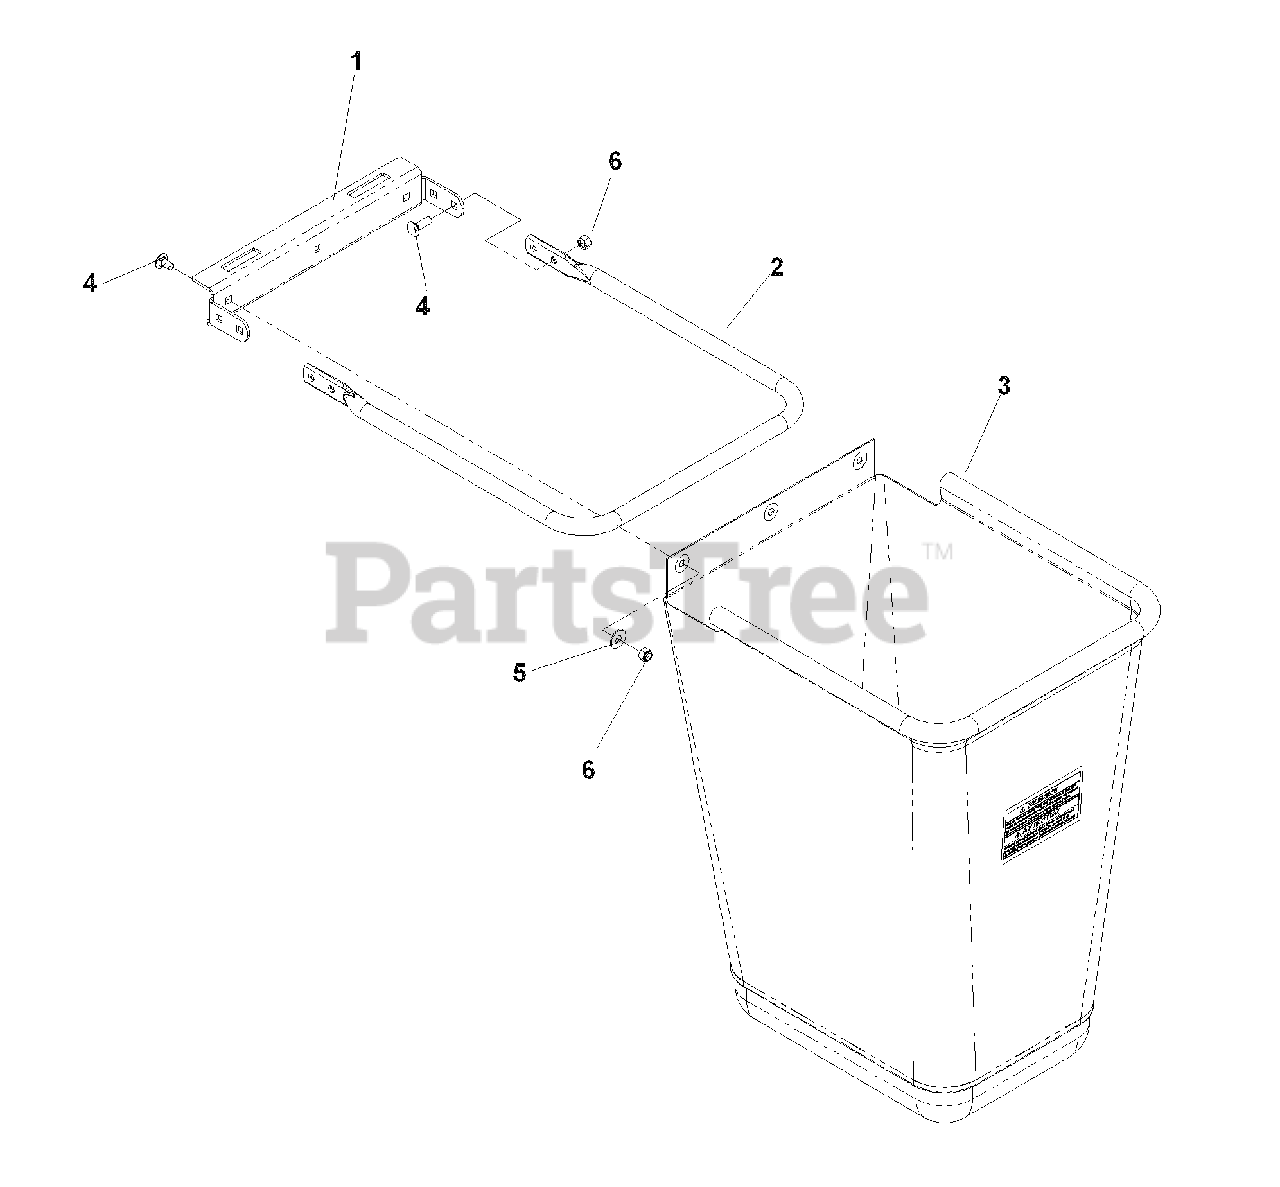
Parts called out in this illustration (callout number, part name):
1	HANGER, BAG
2	TUBE, BAG FRAME
3	BAG, SMALL
4	RHSNB, 5/16-18x3/4
5	WASHER, 5/16
6	NUT, 5/16-18, NYLOC
